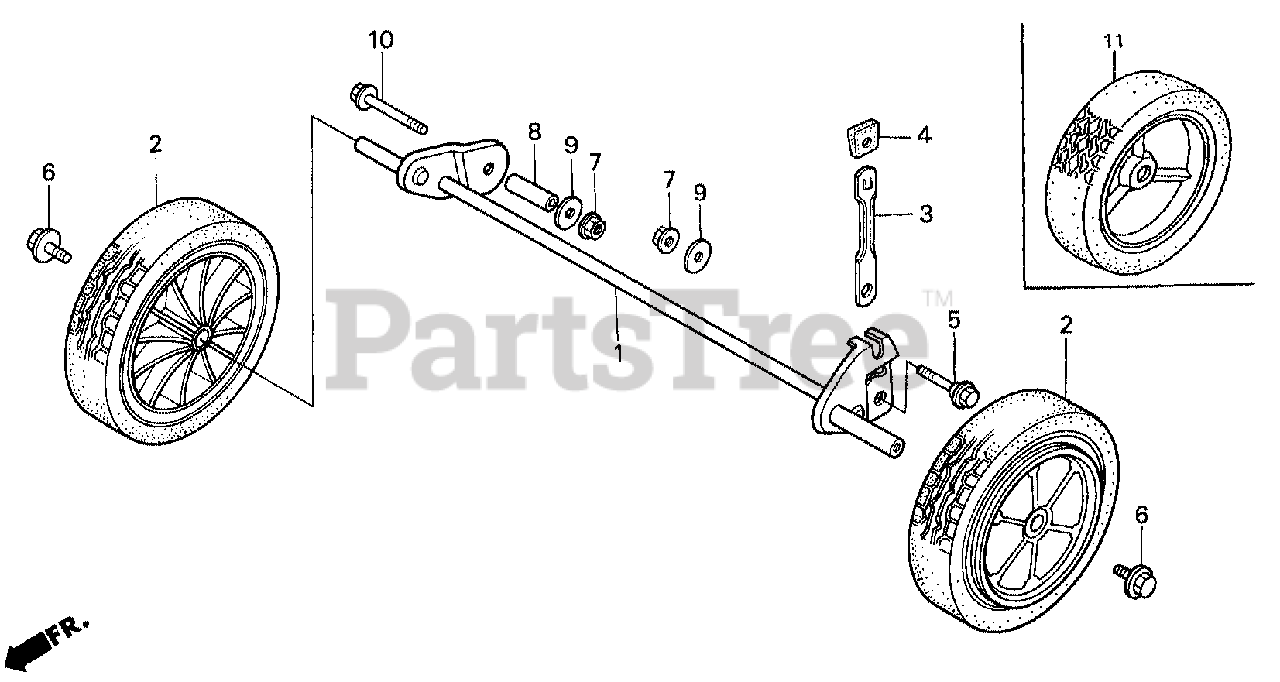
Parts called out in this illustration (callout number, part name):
1	SHAFT, FR. AXLE
2	WHEEL (7X1.5)
2	WHEEL (7") *NH31* (MCKINLEY WHITE)
3	PLATE, FR. ADJUSTING
4	GRIP, ADJUSTER
5	BOLT, ADJUSTING CENTER
6	BOLT, WHEEL
7	NUT, FLANGE (M8X1.25) (SELF-LOCK)
8	COLLAR A, ADJUSTING CENTER
9	WASHER, PLAIN (8MM)
10	BOLT, FLANGE (8X50)
11	WHEEL (7") *NH31* (MCKINLEY WHITE)
